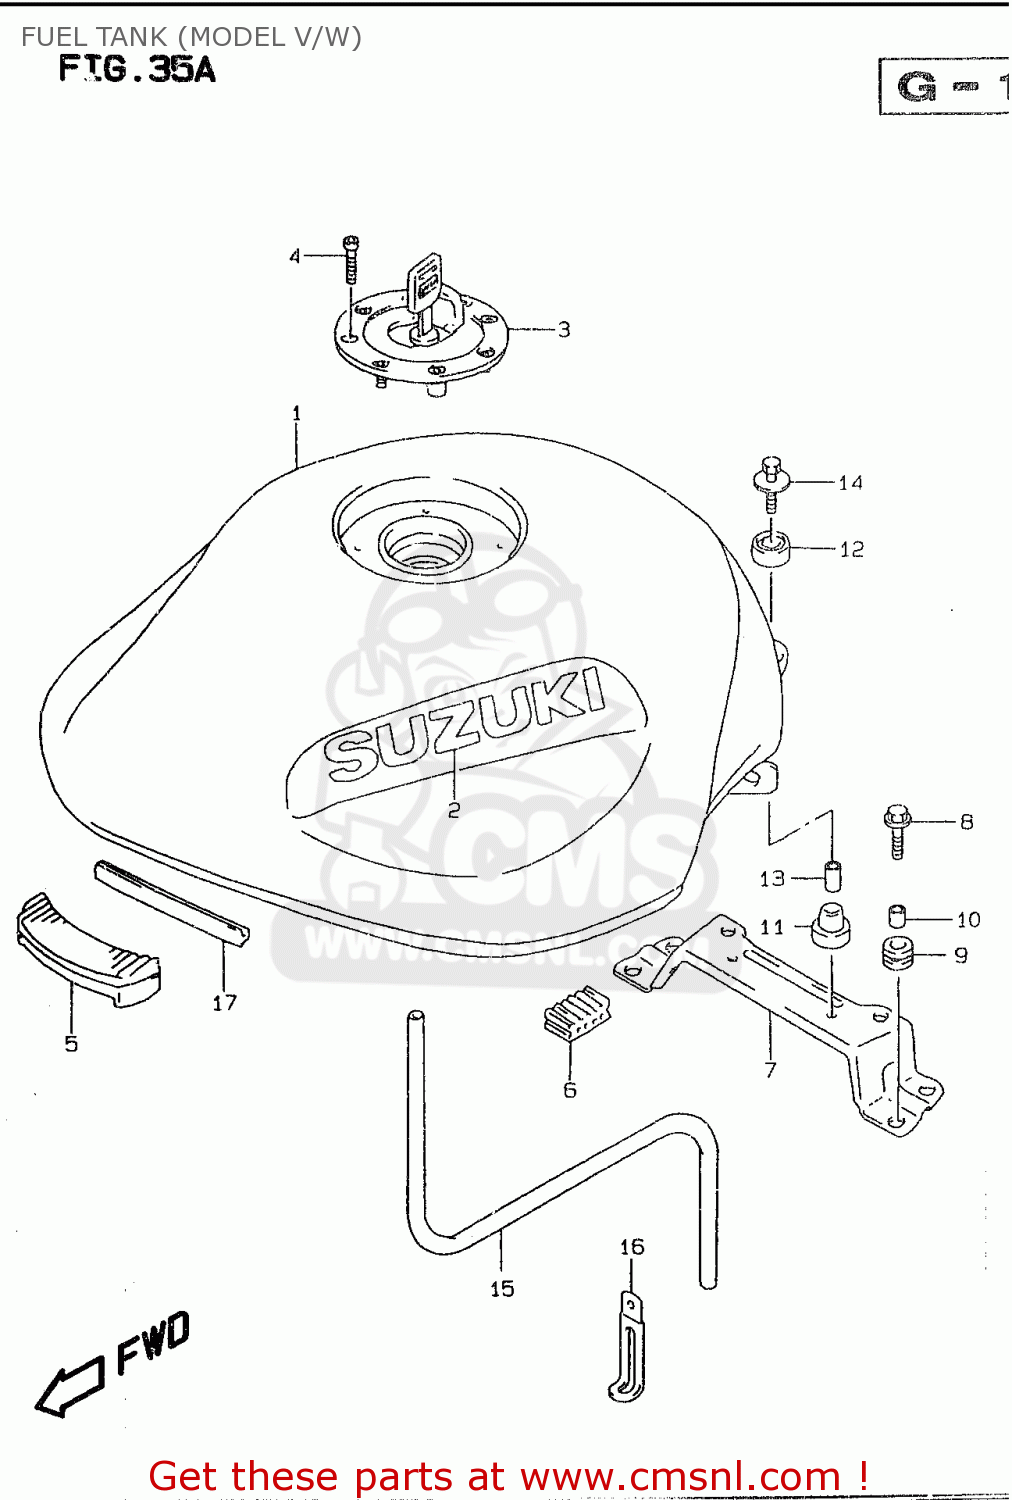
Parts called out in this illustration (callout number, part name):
1	TANK ASSEMBLY,FUEL
2	EMBLEM,FUEL TANK
3	CAP SET,FUEL TANK
4	BOLT(5X20)
5	CUSHION,FUEL TANK FR
6	CUSHION,SEAT(40X20X15)
7	BRACKET,FUEL TANK RR
8	BOLT(6X25)
9	CUSHION
10	WASHER
11	CUSHION
12	CUSHION
13	SPACER(6.5X9X18)
14	BOLT(6X30)
15	HOSE(7X10.2X2000)
16	CLAMP(L:97)
17	MOLDING
